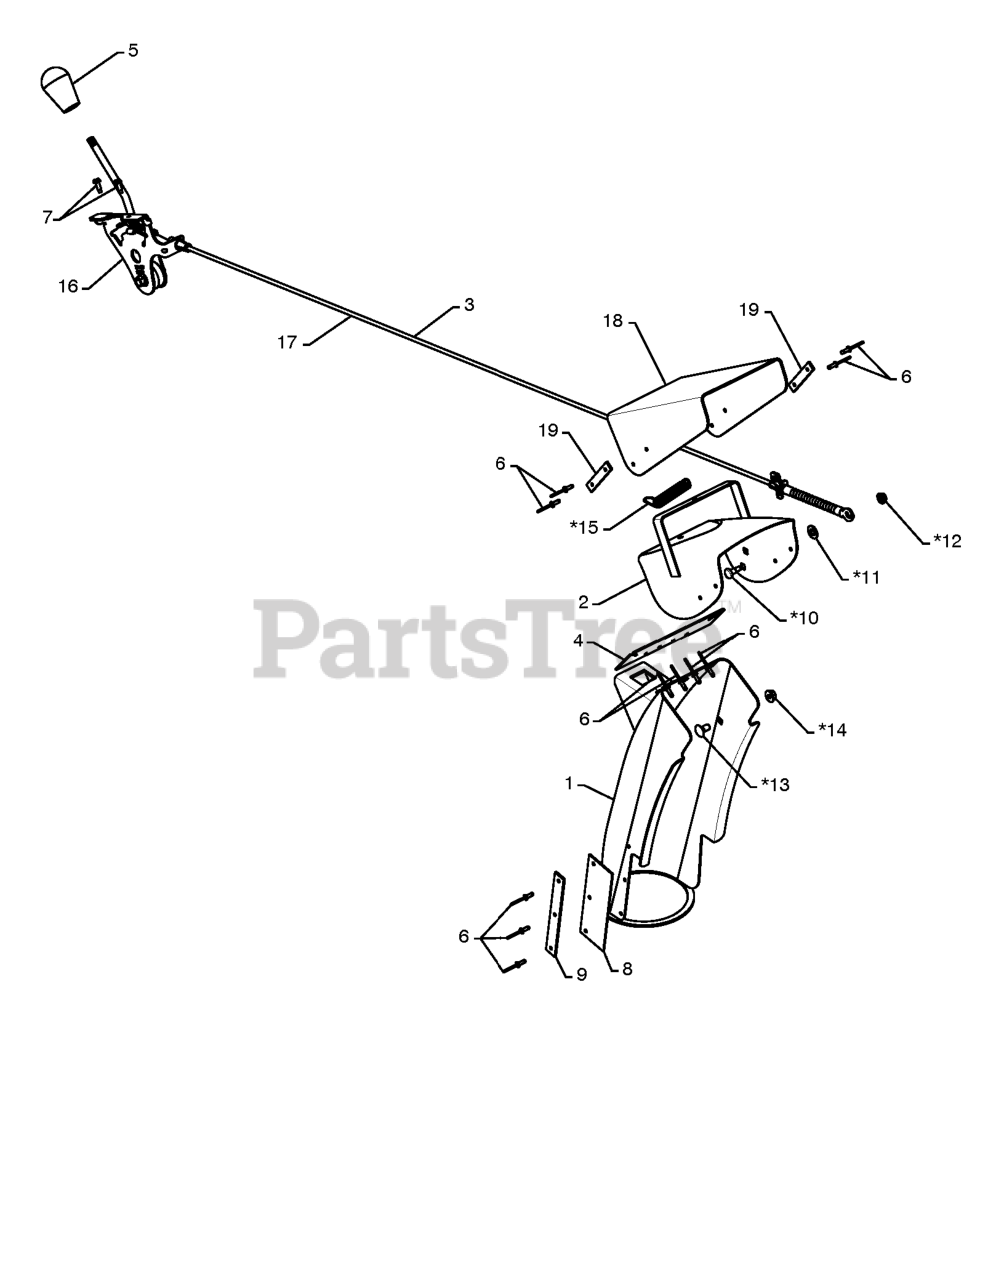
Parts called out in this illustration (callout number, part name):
1	CHUTE.WELDMENT
2	DEFLECTOR.WELDMENT.PNT.ORANGE
3	CONTROL.ASM.DEFLECTOR
4	SEAL.DEFLECTOR
5	KNOB LEVER, BLACK
6	RIVET BLIND
7	SCREW #10-24 X 5/8
8	SHIELD.SNOW.CHUTE
9	STRAP.SHEILD.RETAINER
10	BOLT, SHOULDER
11	WASHER, NYLON FRICTION
12	NUT.HEX.FLANGE.1/4
13	BOLT
14	NUT.LOCK.5/16-18
15	SPRING.DEFLECTOR.REM.CHUTE
16	RP CNTRL.HEAD.ASSEM.DEFLECTOR
17	SERVICE.CHUTE.DEF.CBL.GRY
18	SHIELD.DEFLECTOR.BLACK.SNOW
19	DEFLECTOR SHIELD STRAP
